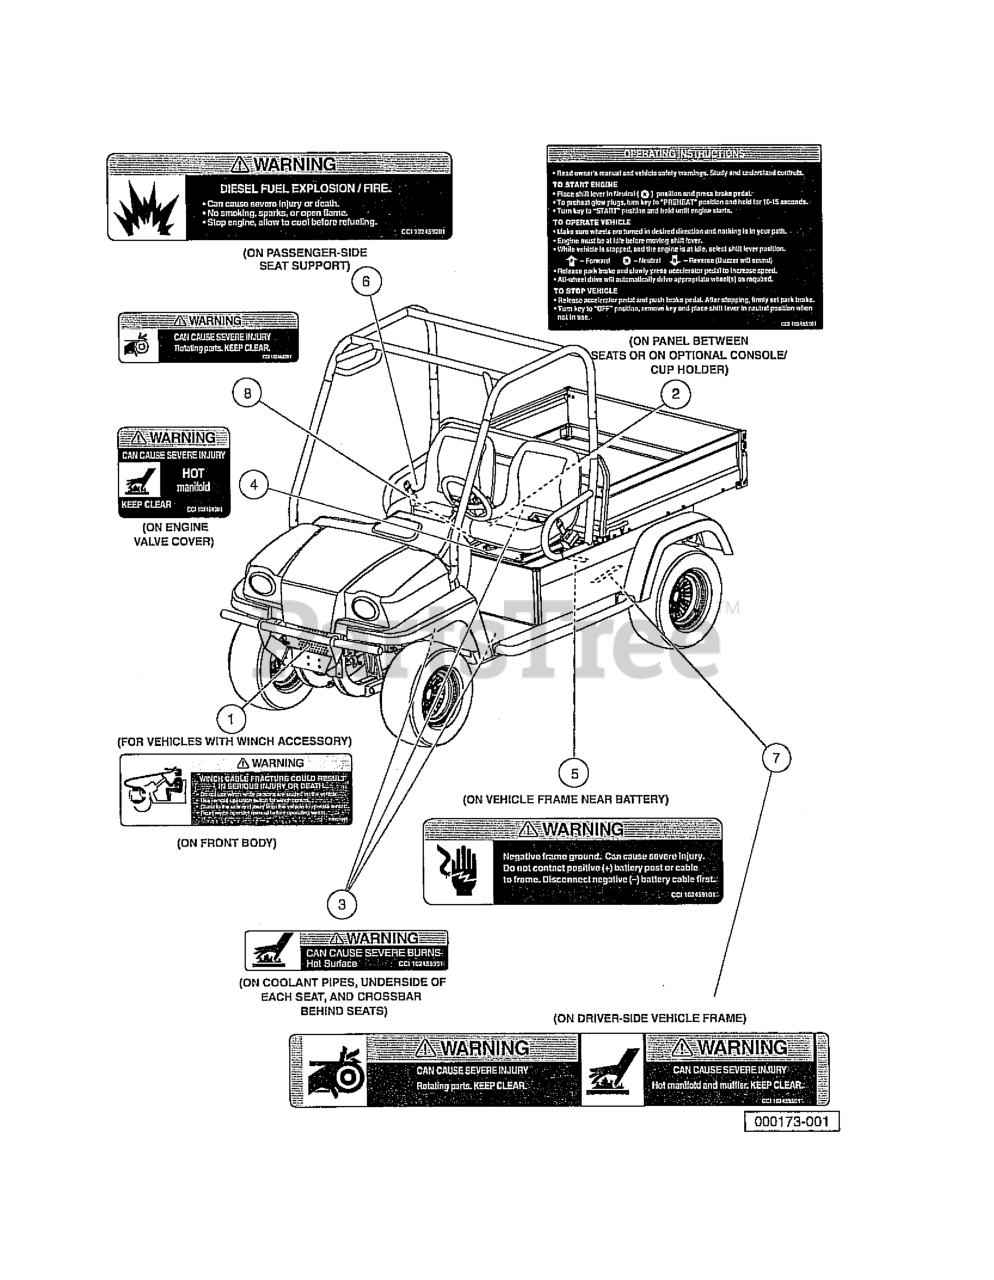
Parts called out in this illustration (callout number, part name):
1	DECAL-WINCH KIT
2	DECAL, OPER INSTR AWD DIESEL
3	DECAL, WARNING HOT SURFACE
4	DECAL, WARNING HOT MANIFOLD
5	DECAL, WARNING GROUND
6	DECAL, WARNING DIESEL FUEL
7	DECAL, WARNING ROTATE/HOT
8	DECAL, WARNING ROTATING PARTS
